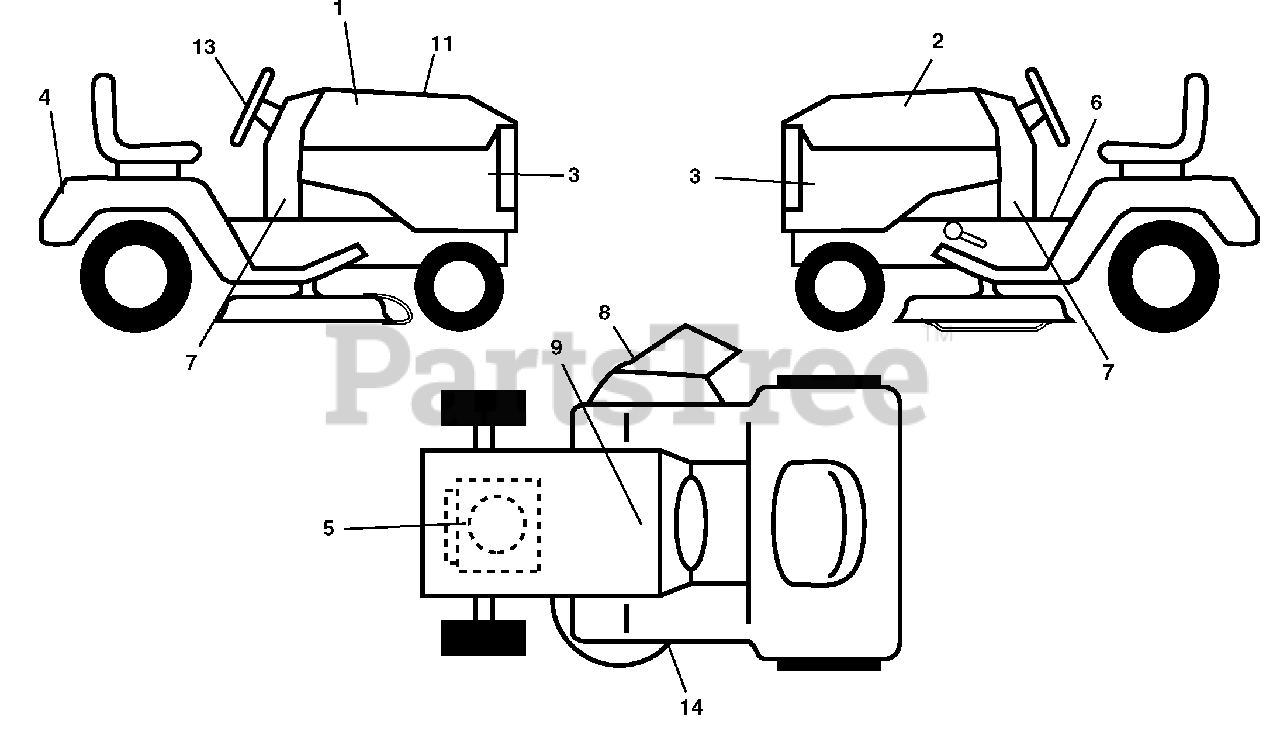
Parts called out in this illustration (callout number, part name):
1	Decal, Hood RH
2	Decal, Hood LH
3	Decal, Side Panel
4	Decal, Fender
5	Decal, Engine
6	Decal, Fender Operator's
7	Decal, Lower Dash
8	Decal, Warning
9	Decal, Battery Dnge/Poi
11	Decal, Replacement
13	Decal, Steering Wheel
14	Decal, Mower Schematic
14	Pad, Footrest, RH
14	Decal, Bypass
14	Pad, Footrest, LH
14	Manual, Operator's (Eng/French)
14	Manual, Parts
